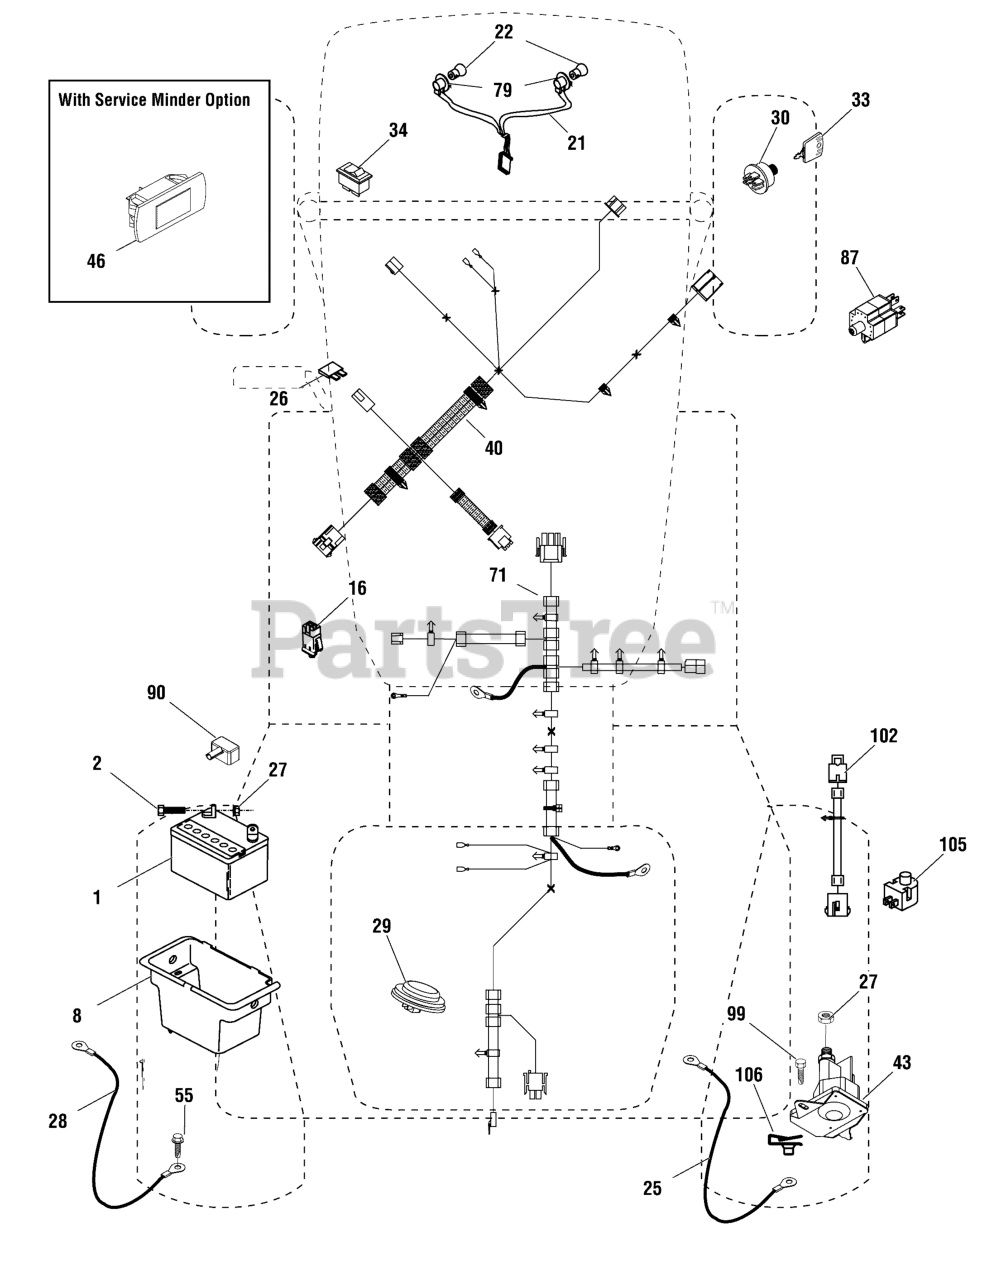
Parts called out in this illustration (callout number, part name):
1	BATTERY
2	BOLT, Hex Head, 1/4-20 UNC x 3/4
8	BOX, Battery
16	SWITCH, Interlock Push-In
21	HARNESS Socket Light w/4152J
22	BULB, Light
25	CABLE, Starter
27	NUT, Keps Hex 1/4-20 UNC
28	CABLE, Ground
29	SWITCH, Seat
30	SWITCH, Ign
33	KEY/CHAIN
34	SWITCH, Light / Reset
40	HARNESS, Ignition Dash
43	SOLENOID
55	SCREW, Thread Rolling, 5/16-18 x 3/4
71	HARNESS, Ignition Chassis
79	BULBHOLDER, Assembly Incandescent
87	SWITCH, Interlock Clutch Cable
90	COVER, Terminal Battery
99	SCREW
102	HARNESS, Pigtail
105	SWITCH, Reverse
106	PALNUT
